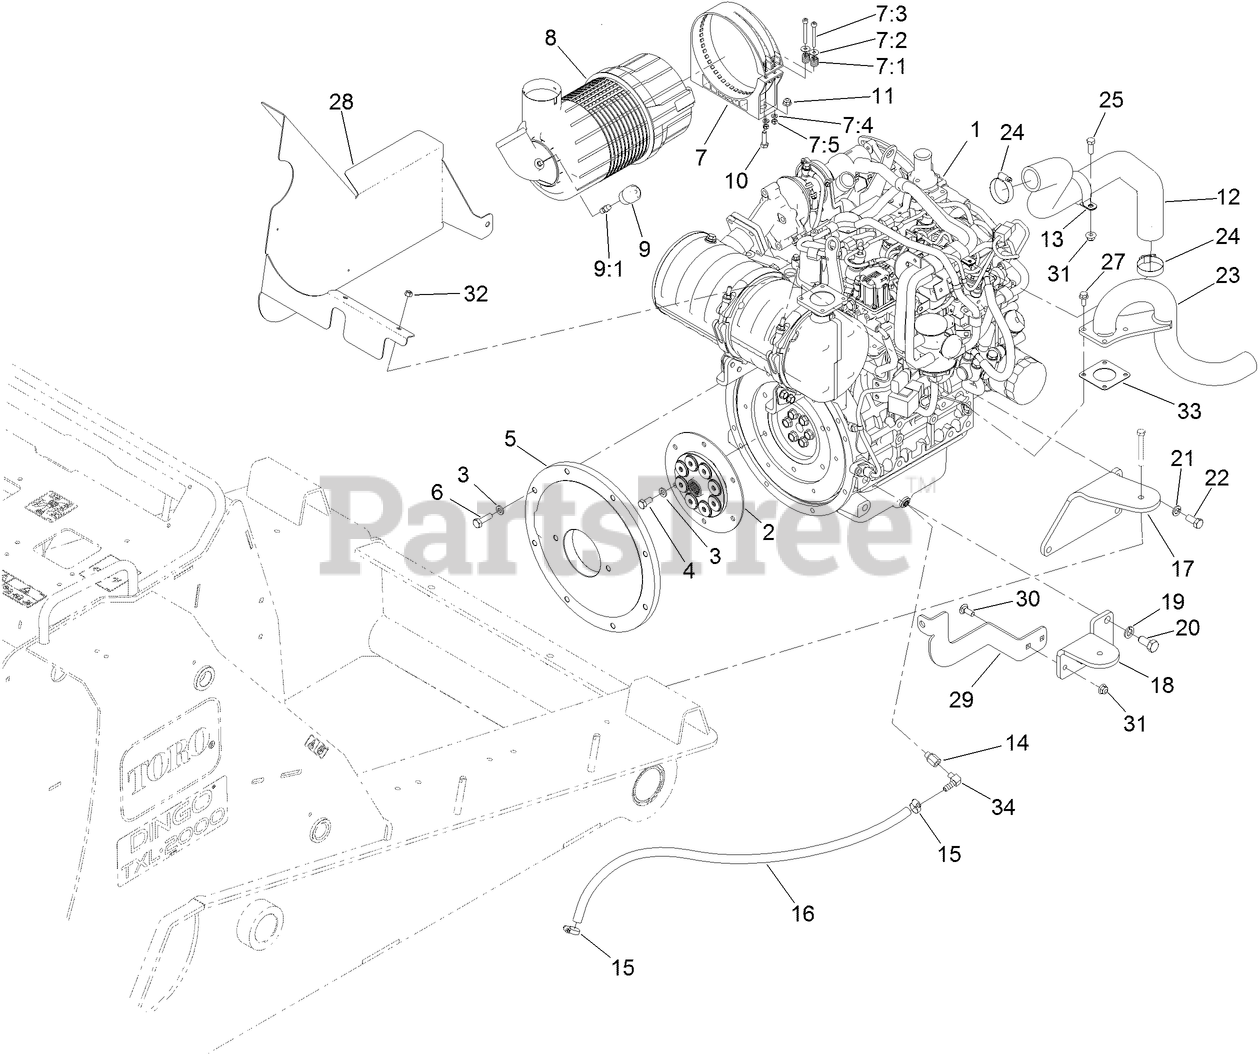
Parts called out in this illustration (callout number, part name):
1	ENGINE-KUBOTA
2	COUPLER-SPRING, FLYWHEEL
3	WASHER-HARDENED
5	PLATE-FLYWHEEL
6	SCREW-HH
7	STRAP-CLEANER, AIR
7:1	SPRING
7:2	WASHER-FLAT
7:3	SCREW-HH
7:4	WASHER-FLAT
7:5	NUT-LOCK
8	AIR CLEANER ASM
9	INDICATOR
9:1	ADAPTER-INDICATOR
10	SCREW-HH
11	NUT-HF, NI
12	HOSE-AIR, COOLER
13	CLAMP-R
14	ADAPTER-DRAIN
15	CLAMP-HOSE
16	HOSE-DRAIN
17	MOUNT-ENGINE
18	MOUNT-ENGINE
19	WASHER-LOCK, SPRING
20	SCREW-HH
21	WASHER-LOCK
22	SCREW-HH
23	PIPE-EXHAUST
24	CLAMP-HOSE
25	SCREW-HH
27	SCREW-HHF
28	SHIELD-ALTERNATOR
29	BRACKET-PUMP, RH
30	BOLT-CARR
31	NUT-HF, NI
32	NUT-LOCK, NI
33	GASKET-MUFFLER
34	FITTING-90 DEG
